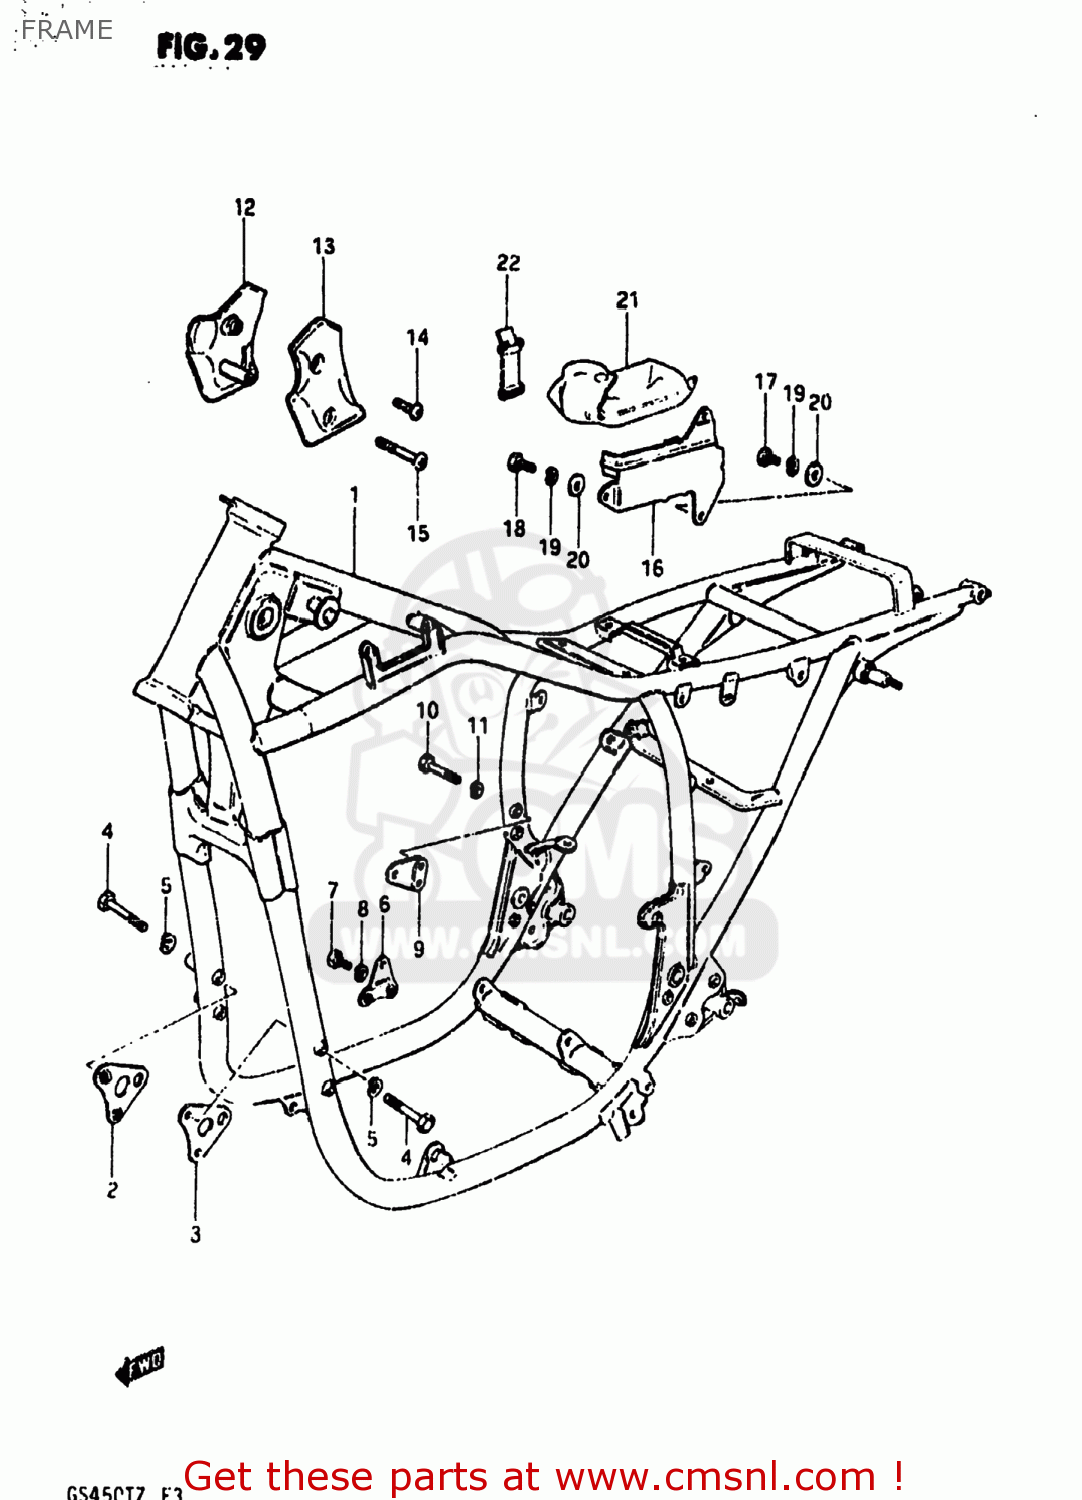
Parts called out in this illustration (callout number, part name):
1	FRAME
2	PLATE,ENGINE MOUNTING
3	PLATE,ENGINE MOUNTING
4	BOLT
5	LOCK WASHER
6	PLATE,ENGINE MOUNTING
7	BOLT
8	LOCK WASHER
9	PLATE,ENGINE MOUNTING
10	BOLT 8X45
11	LOCK WASHER
12	COVER,FRAME HEAD,RIGHT
13	COVER,FRAME HEAD,LEFT
14	(5X20) CROSS SCREW
15	SCREW, LOWER
16	HOLDER,TOOL
17	SCREW 6X12
18	SCREW
19	LOCK WASHER
20	WASHER
21	TOOL SET
22	BAND
